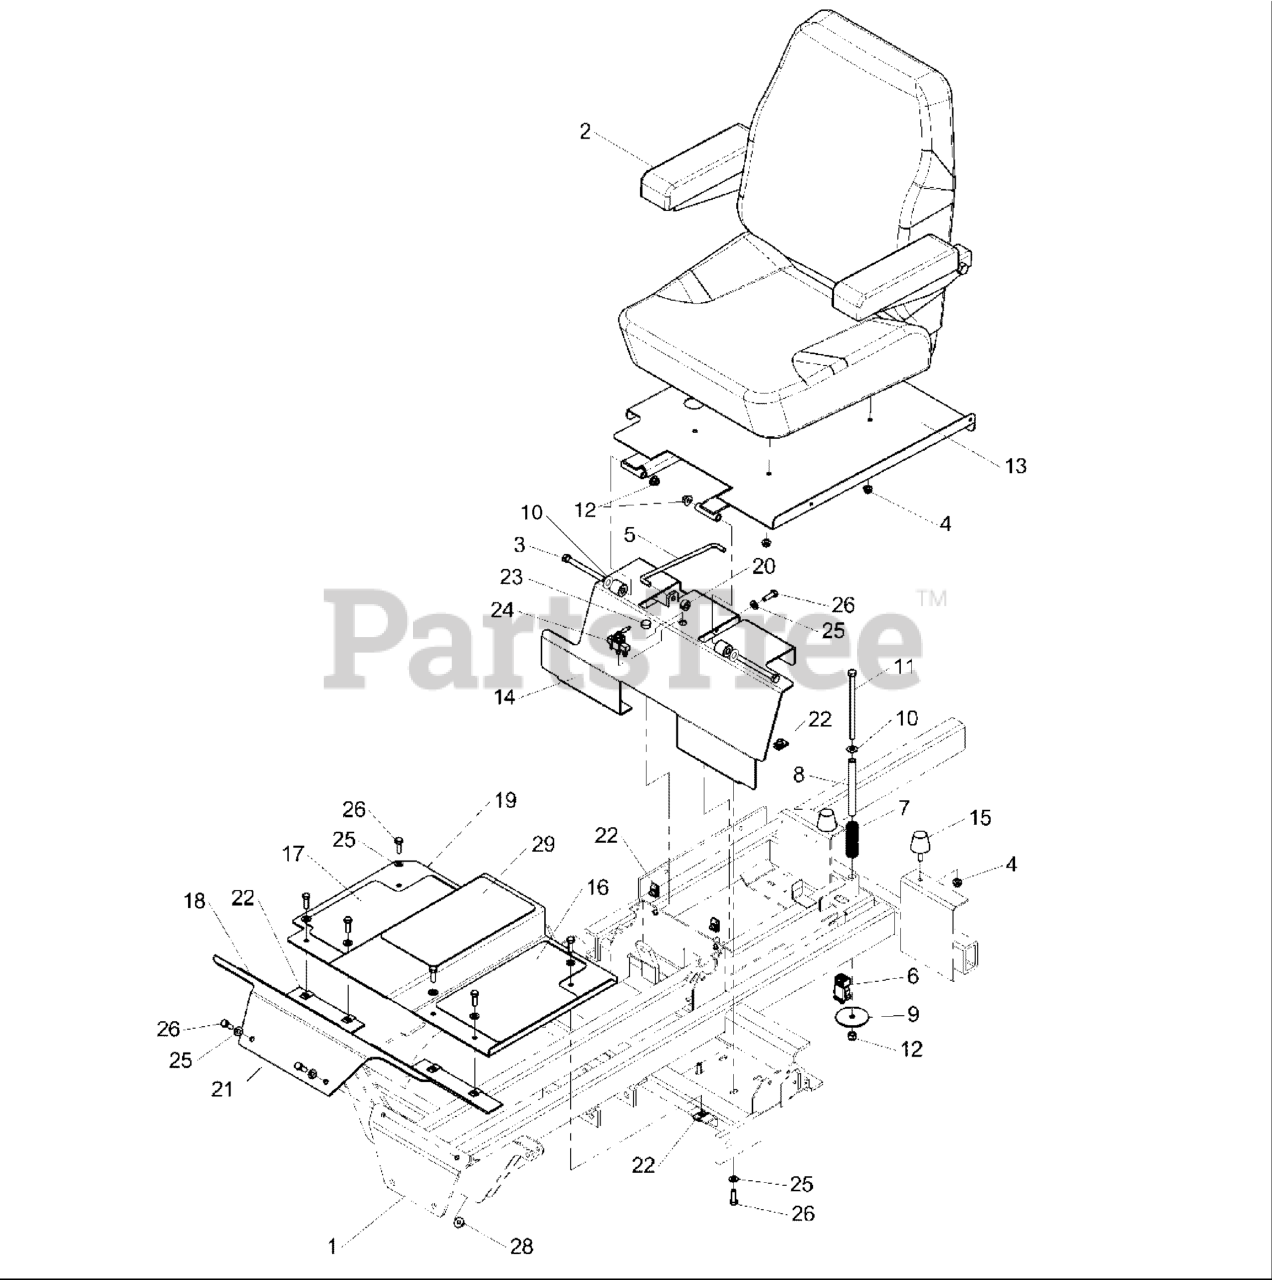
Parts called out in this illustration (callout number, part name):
1	MAIN FRAME
2	SEAT, DELUXE, GRAY (COMPLETE)
2	SEAT BOTTOM COVER
2	CUSHION, BACK COVER
2	ARM REST SET
2	ARM REST PAD
2	SEAT ADJUSTER RAILS
2	SPRING, EXTENSION, SEAT ADJUSTMENT (YEL OR BLK)
3	BOLT, 3/8-16 X 4" GD5 CZ
4	NUT, 5/16-18 HEX NYLOCK FLANGE
5	ROD, SEAT STOP
6	SWITCH, PLUNGER, NC/NC SNAP-IN
7	SPRING, COMP, .835 X.105 X4.26
8	SPACER, .38 X .50 X 5.06
9	WASHER, .39 X 2.50 X .125
10	WASHER, 3/8 SAE
11	BOLT, 3/8-16 X 6" GD5 CZ
12	NUT, 3/8-16 HEX NYLOCK FLANGE
13	WELD, SEAT MOUNT
14	WELD, SEAT MOUNT
15	BUMPER, RUBBER 5/16-18
16	SAFETY WALK,FLOOR - LH
17	SAFETY WALK,FLOOR - RH
18	SAFETY WALK,ANGLED FLOOR
19	PLATE, FLOOR
20	COLLAR, 5/16" SET
21	ANGLED, FLOOR
22	BODY CLIP, 5/16-18-7GA MATERIAL
23	HOLE PLUG, 5/8" SNAP-IN
24	VALVE, FUEL SHUT OFF
25	WASHER, 5/16" SAE
26	BOLT, 5/16-18 X 1"
28	NUT, 5/16-18 HEX SERRATED FLANGE (LARGE)
29	SAFETY WALK, 11.25 X 6.00
